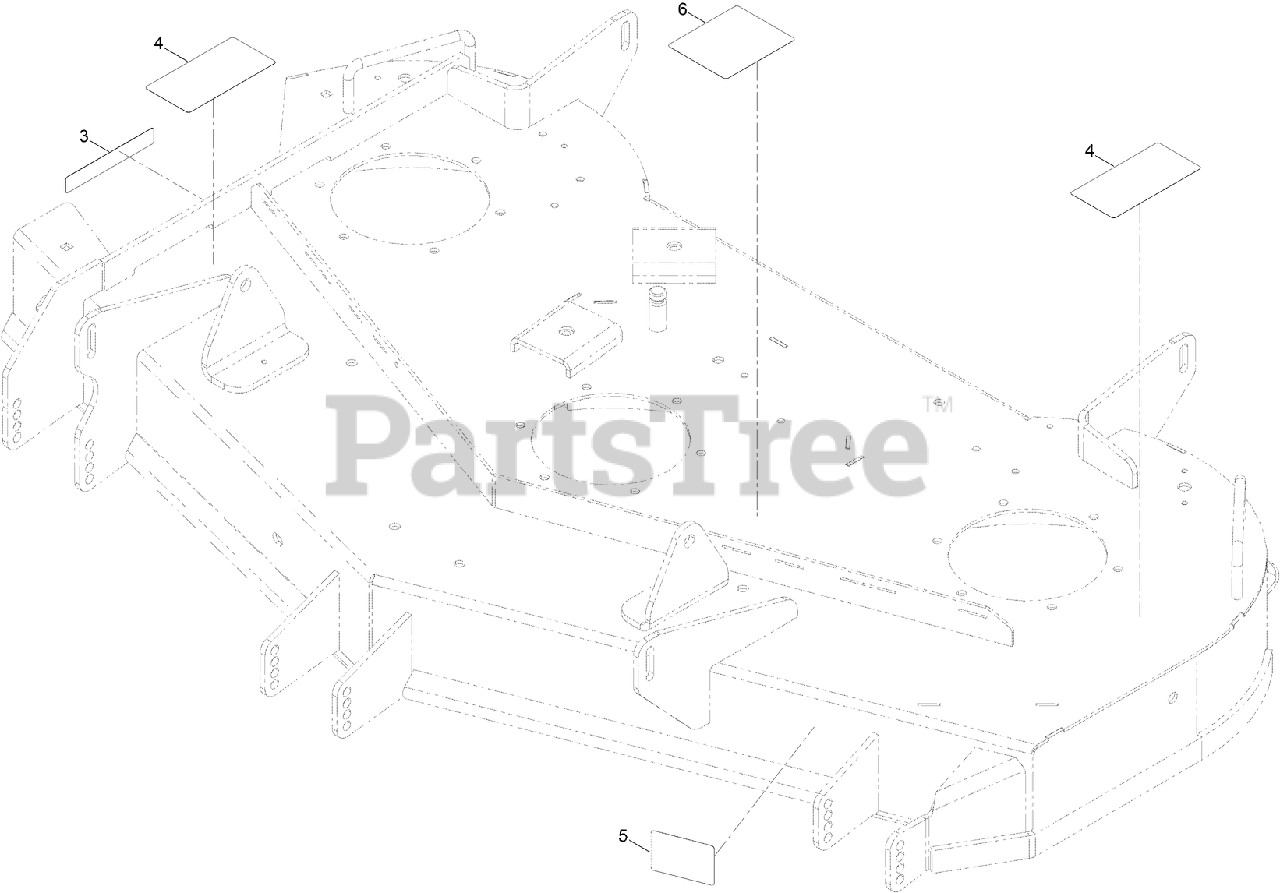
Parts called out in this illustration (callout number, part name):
3	DECAL-DANGER
4	DECAL-DANGER, DECK
5	DECAL-SCALP, ANTI
6	DECAL-ROUTING, BELT
